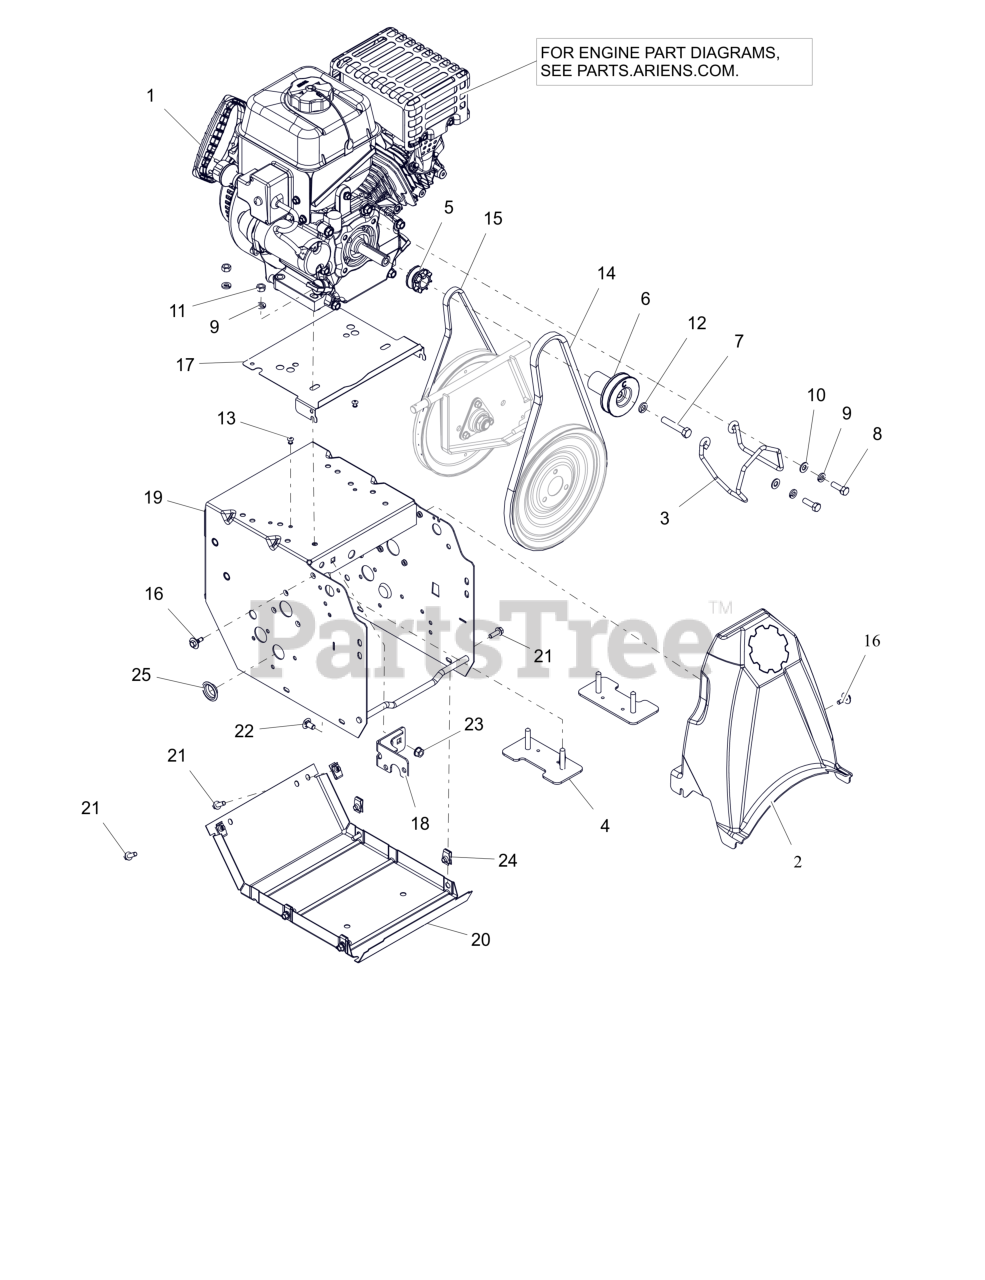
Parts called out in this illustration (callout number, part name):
1	ENGINE, ARIENS AX208 120V
2	COVER- CLASSIC BELT
3	FINGER, BELT
4	STRAP, ENGINE BOLT-WELDMENT
5	SHEAVE, TRACTION
6	SHEAVE, ATTACHMENT SINGLE GRV
7	BLT, HEX .38-24X2.00 G5 ZCC
8	BLT, HEX 0.3125-24X1 G5 ZCC
9	WSHR, LK-HVY .312X.097 ZCC
10	WSHR,FLT .344X.688X.065 ZCC
11	NUT, HEX .312-18 ZCC
12	WSHR,LK-REG .375X.094 ZCC
13	RVT, POP .1875 ZCC
14	V-BELT, HA-RAW EDGE
15	V-BELT, 3L-WRAPPED
16	SCR-TAP .25-20X.5 CAPTIVE
17	BAFFLE, COMPACT
18	WELDMENT, FRAME BRACKET
19	FRAME, MAIN
20	COVER, BOTTOM
21	BLT, HWH .25-20X.75 G5 ZCC
22	BLT, RHSSN .31-18X.625 G5 ZCC
23	NUT-LK-TOP-FLG .312-18 GF ZCC
24	NUT-RTNR .25-20X.56
25	PLUG, HOLE - 1.00" FLEXTEMP
